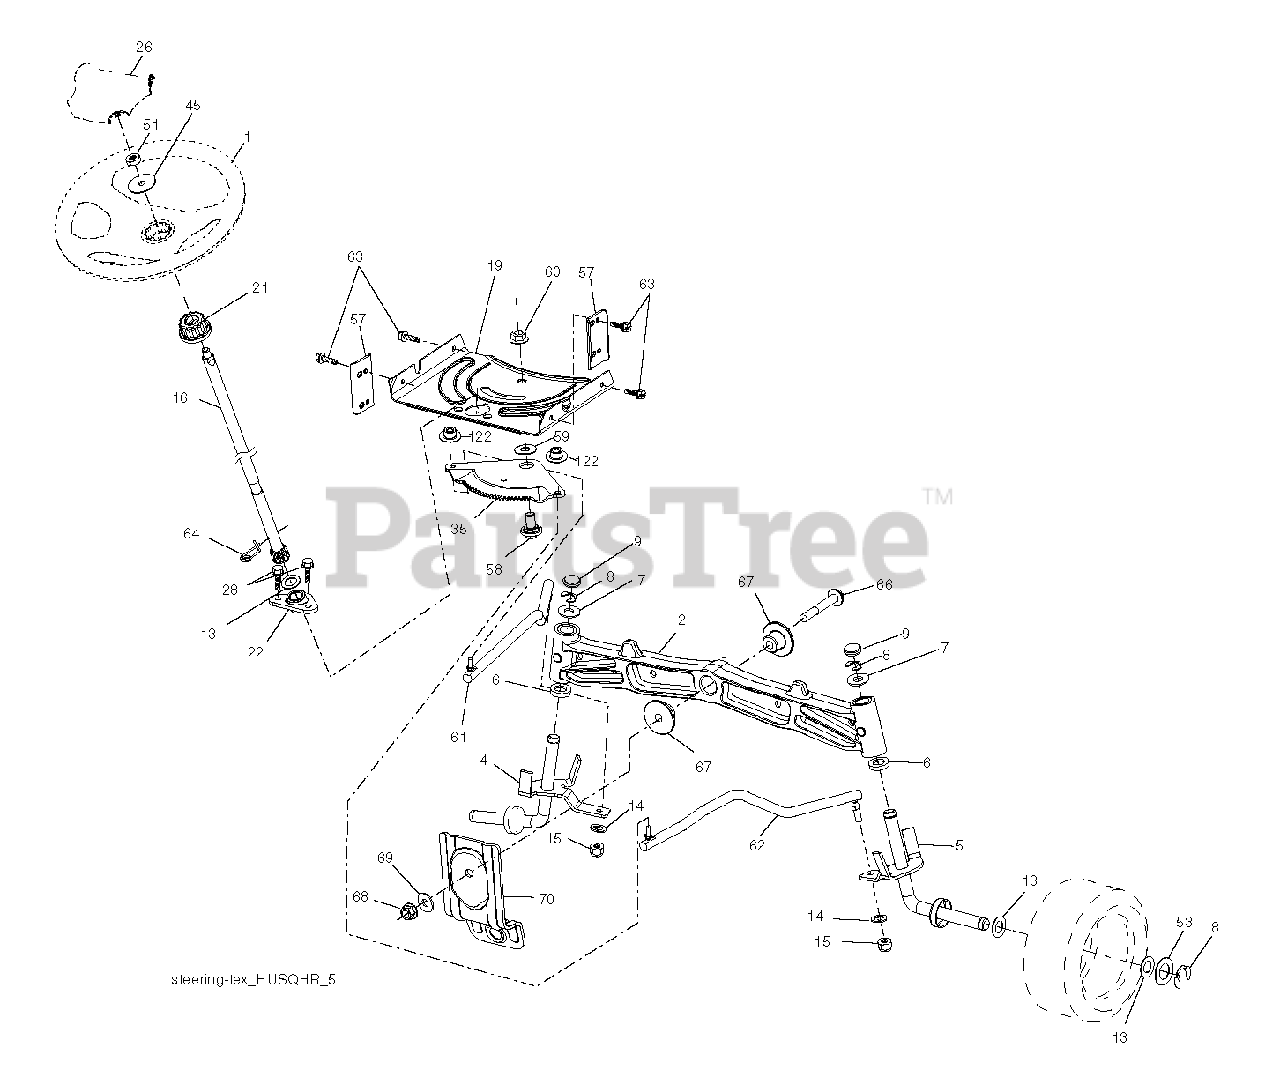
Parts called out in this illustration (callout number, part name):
1	WHEEL.STEER.HUSQ.SR.498.OVMLD
2	AXLE.CAST.IRON
4	SPINDLE.WELDED.LH.15"TEX
5	SPINDLE.WELDED.RH.15"T
6	THRUST WASHER
9	CAP.SPINDLE.BLACK
14	WASHER, LOCK 3/8
15	NUT CROWNLOCK 3/8-24
16	SHAFT, STEERING
19	PLATE.STEER.DDL.NLT/NG
21	ADAPTER, WHEEL STNG..
22	STEERING.SUPT.LOWER.
26	INSERT.CAP.WHL.STRG.HUSQ.PREM
28	SCREW, 3/8-16X3/4
35	GEAR.SECTOR.PLATE.DDL.
45	WASHER 9/16"ID, 2 3/8"OD
51	NUT.HEX.1/2-20
53	WASHER.HARDENED
57	BRACKET.UPSTOP.TEX
58	BOLT.SHOULDER.SECTOR.P
59	WASHER.THURST.SECTOR.S
60	NUT FLANGE LOCK 5/8-11
61	DRAGLINK.LH.BALLSTUD.D
62	DRAGLINK.RH.BALLSTUD.D
63	SCREW
64	RETAINER.CLIP.SPRING.S
66	BOLT HEX FGHD 7/16-14 X 3 SERR
67	BUSHING.PM.FRONT AXLE
68	NUT.LOCK.FLANGE.7/16
69	WASHER.1.5X.505X.118
70	BRKT.DECK.SUSPENSION.F
122	CAP.GEAR.SECTOR.TEX
